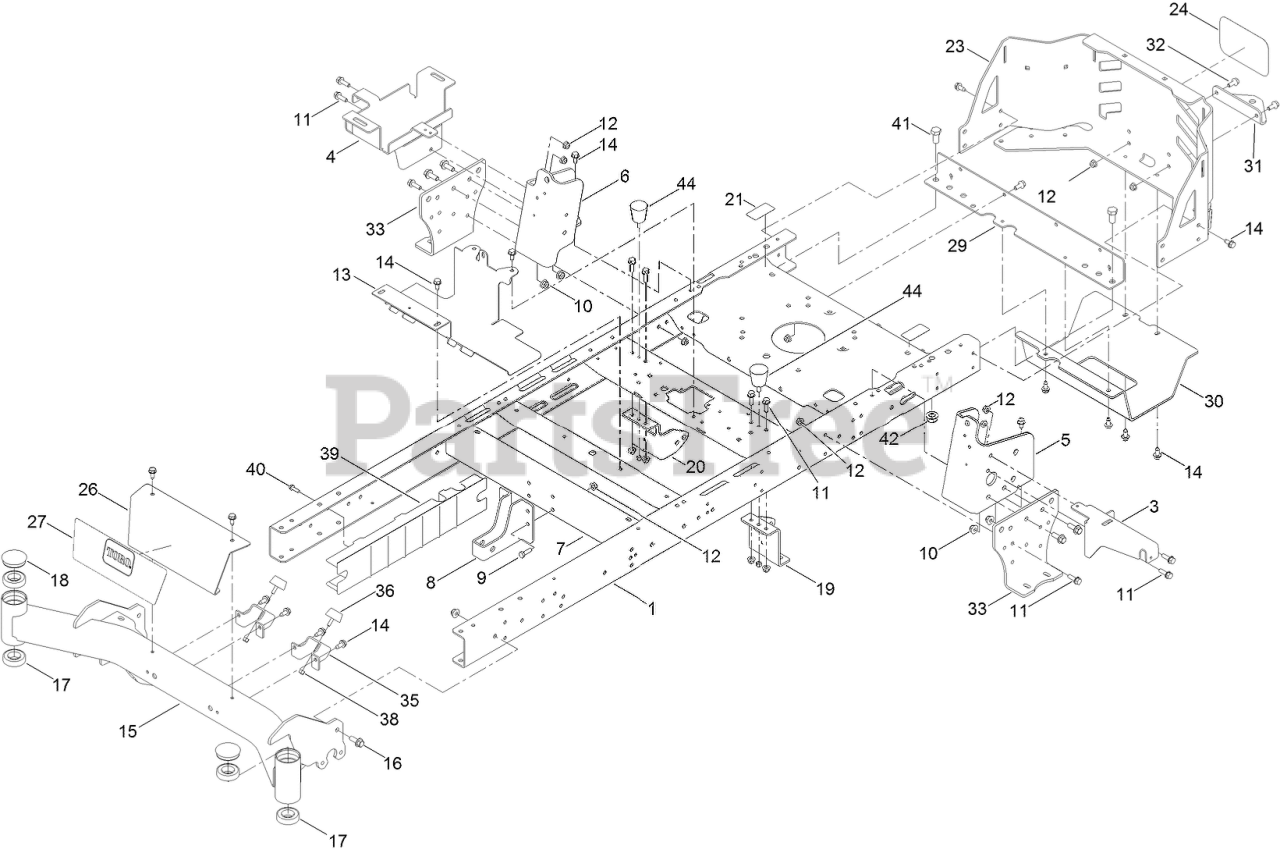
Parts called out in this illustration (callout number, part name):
1	FRAME ASM
3	BRACKET-SUPPORT, POD (LH)
4	TRAY-BATTERY
5	BRACKET-MOUNTING, LH
6	BRACKET-MOUNTING, RH
7	BRACE-CROSS, LOWER
8	BRACKET-MOUNT DAMPER, LOWER
9	SCREW-HH
10	NUT-HF, NI
11	SCREW-HHF
12	NUT-HF, NI
13	BRACKET-MOUNT
14	SCREW-HWHTF
15	AXLE-FRONT
16	SCREW-HHF
17	BEARING-BALL
18	CAP-GREASE
19	MOUNT-HYDRO, FRONT (LEFT)
20	MOUNT-HYDRO, FRONT (RIGHT)
21	DECAL-BYPASS
23	GUARD-ENGINE
24	DECAL
26	PLATE-FRONT
27	DECAL-TIMECUTTER HD
29	CROSSMEMBER-REAR
30	GUARD-MUFFLER
31	BRACKET-HITCH
32	SCREW-HHF
33	MOUNT-HYDRO
35	BRACKET-STOP, BUMP
36	BUMPER
38	NUT-LOCK, NI
39	GUARD-RAIL
40	SCREW-HWH
41	SCREW-HH
42	NUT-LOCK
44	BUMPER-RUBBER
